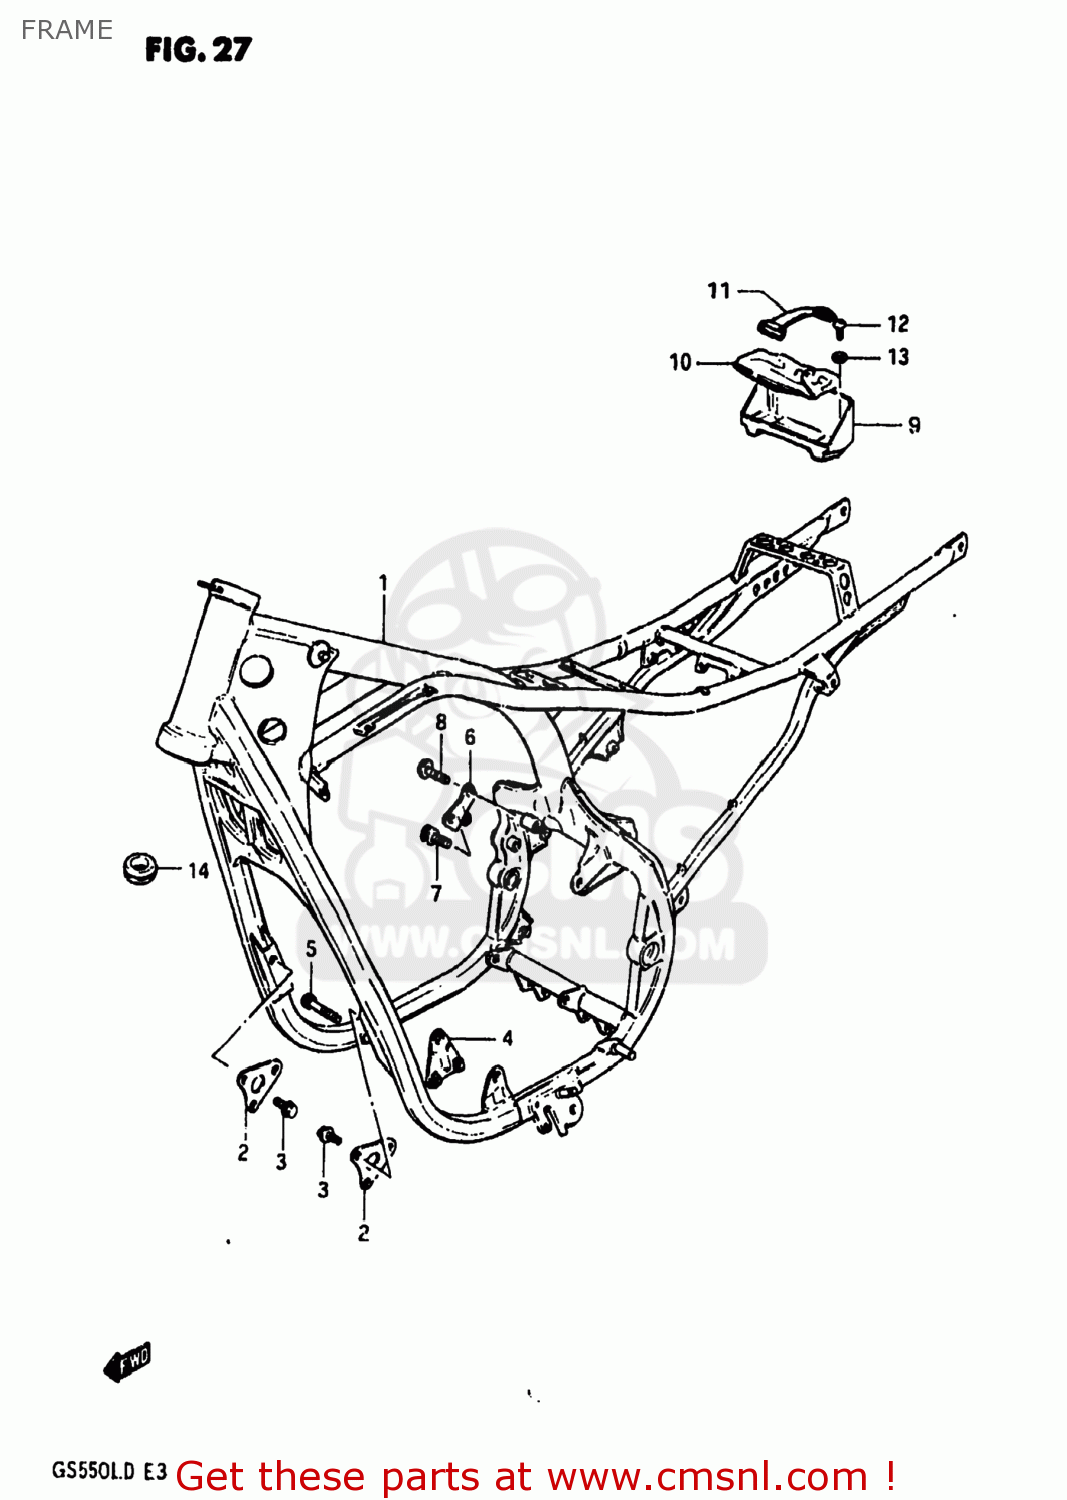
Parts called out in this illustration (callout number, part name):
1	FRAME
2	PLATE,ENGINE MOUNTING
3	BOLT
4	PLATE,ENGINE MOUNTING
5	BOLT
6	PLATE,ENGINE MOUNTING NO.4
7	BOLT
8	BOLT
9	HOLDER,TOOL
10	TOOL ASSY
11	BAND
12	SCREW
13	WASHER
14	GROMMET
